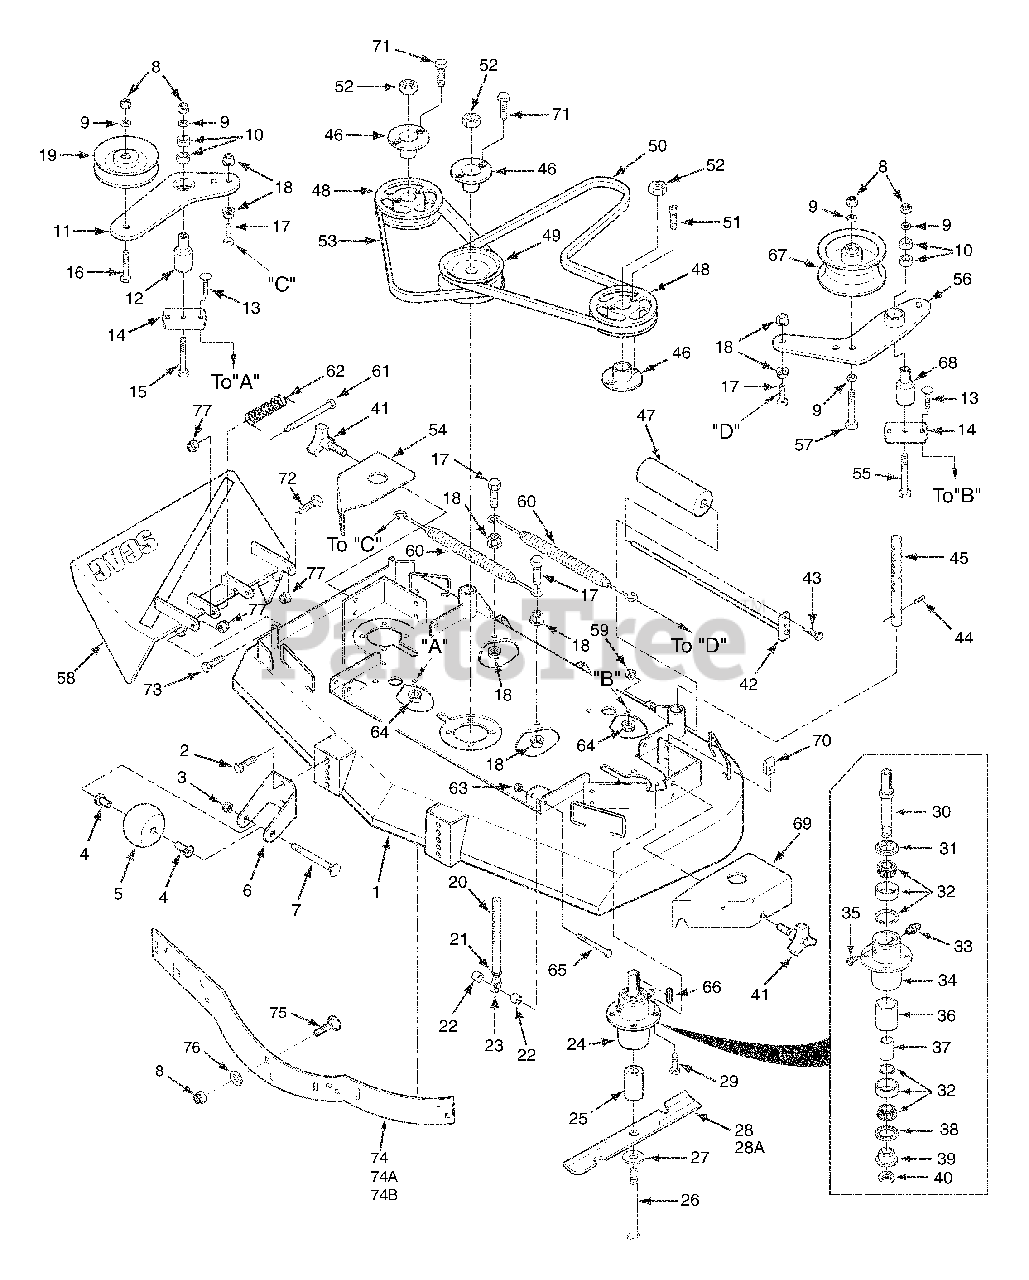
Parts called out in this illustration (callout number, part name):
1	Cutter Deck W/ Decals (small frame)
1	Cutter Deck W/ Decals (large frame)
2	Capscrew, 3/8-16 x 1" Serr. Flng.
3	Lock Nut, 3/8-16 Center Lock
4	Bushing, .376" ID Oilite
5	Wheel, Anti-Scalp
6	Bracket, Anti-Scalp Wheel
7	Bolt, Carriage 3/8-16 x 4"
8	Hex Nut, 3/8-16 Elastic Stop
9	Flatwasher, 3/8" (.938 x .391 x .105)
10	Ball Bearings
11	Idler Arm RH
12	Pivot, Idle - Short
13	Bolt, Carriage 5/16-18 x 1"
14	Base, Idler Pivot
15	Capscrew, Hex Head 3/8-16 x 2-1/2"
16	Capscrew, Hex Head 3/8-16 x 2"
17	Capscrew, Hex Head 3/8-16 x 1-1/2"
18	Nut, 3/8-16 Serrated Flange
19	Pulley, Idler
20	Pin Assembly
21	Nut, 3/8-24 Jam
22	Spacer, Deck Adjustment Pin
23	Rod End, Male 3/8-24
24	Spindle Assembly
25	Spacer, Spindle
26	Bolt,Hex Head 5/8-11 x 9-1/2"
27	Flatwasher, 5/8 W
28	Cutter Blade 18"
28A	Cutter Blade 18" Hi Lift
29	Bolt, Hex Head 5/16-18 x 1-1/2"
30	Spindle Shaft
31	Seal, Cutter Spindle - Top
32	Tapered Bearings (Two)
33	Grease Fitting
34	Spindle Housing
35	Relief Fitting, Cutter Spindle
36	Spacer Outside
37	Spacer, Inside
38	Seal, Cutter Spindle - Bottom
39	Spindle Bushing
40	Nut, Spindle
41	Wing Nut, 3/8-16
42	Roller Shaft (small frame)
43	Bolt, Hex Head 5/16-18 x 1"
44	Pin, Slotted Spring 3/16 x 1-1/2"
45	Pin, Deck Adjustment Rear
46	Tapered Hub
47	Guide, Roller
48	Pulley
49	Pulley, 5.75 Double Groove
50	Belt, Deck Drive
51	Capscrew, Sckt. Hd. 1/4-20 x 1-3/8"
52	Hex Nut, 5/8-11
53	Belt, Cutter Deck RH
54	Belt Cover, RH
55	Capscrew, HH 3/8-16 x 3-1/4"
56	Idler Arm Weldment
57	Capscrew, Hex Head 3/8-16 x 3-3/4"
58	Discharge Chute
59	Nut, 5/16-18 Serrated Flange
60	Spring, Deck Idler
61	Bolt, Hex Head 5/16-18 x 4-1/4"
62	Spring, Chute Return
63	Nut, 3/8-16 Elastic Stop
64	Nut, 5/16-18 Serrated Flange
65	Bolt, Hex Head 3/8-16 x 2-1/2"
66	Key, 1/4" x 1/4" x 2"
67	Pulley, Idler
68	Pivot, Idler - Long
69	Belt Cover LH
70	U-Nut, 3/8-16
71	Bolt, Hex Head 1/4-20 x 1"
72	Bolt, Hex Head 5/16-18 x 1-1/2"
73	Bolt, Hex Head 5/16-18 x 1-3/4"
74A	Baffle Weldment 52A
75	Bolt, Carriage 3/8-16 x 1"
76	Flatwasher, 3/8" (.391 x .938 x .105)
77	Hex Nut, 5/16-16 Elastic Stop
